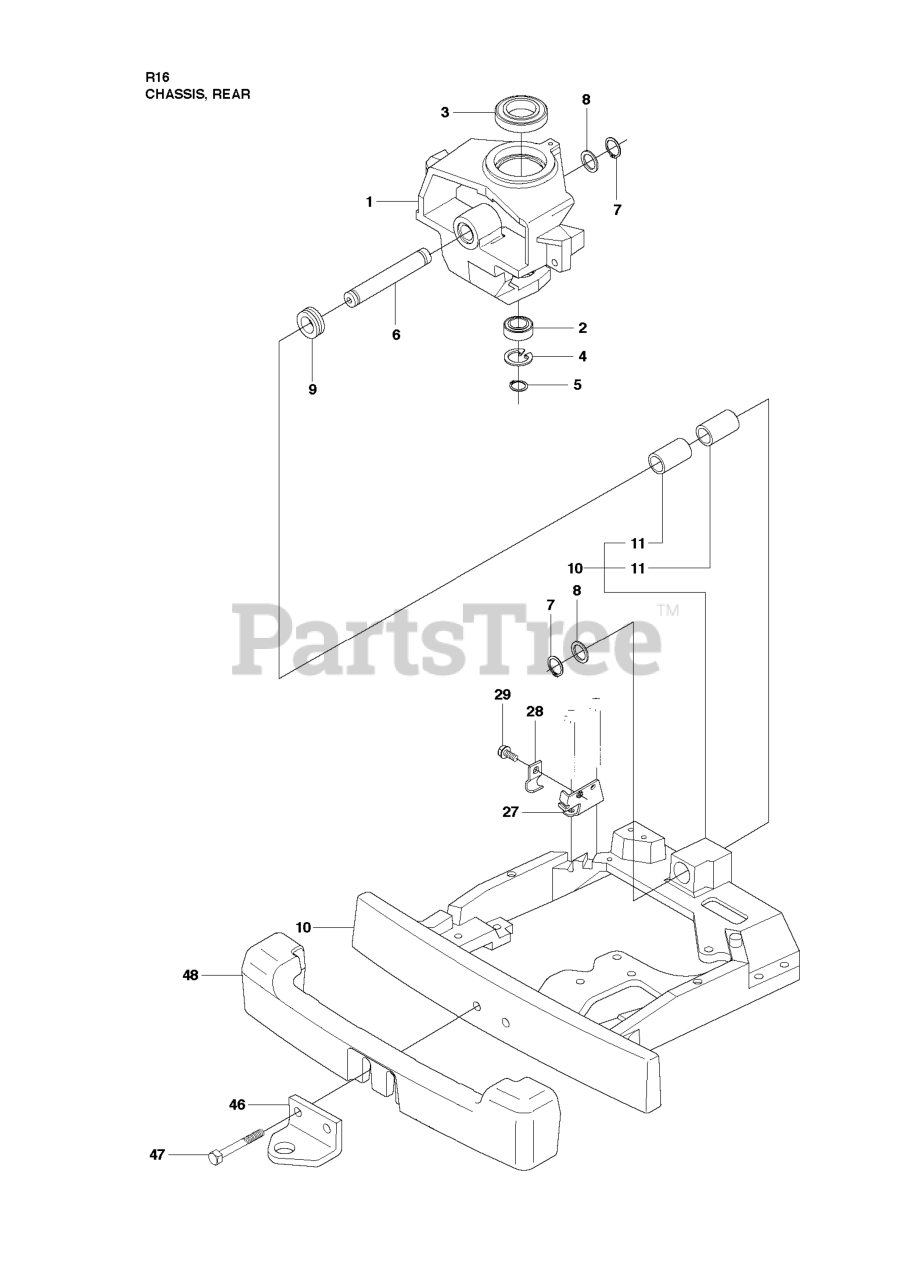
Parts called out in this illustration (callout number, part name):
2	Ball Bearing 6005-2rs
3	BALL BEARING 6010 2RS1
4	CIRCLIP SGH 47
5	RETAINING RING SGA 25
7	RETAINING RING SGA 25
47	REPL BY 725 25 00-71
48	COUNTERWEIGHT
